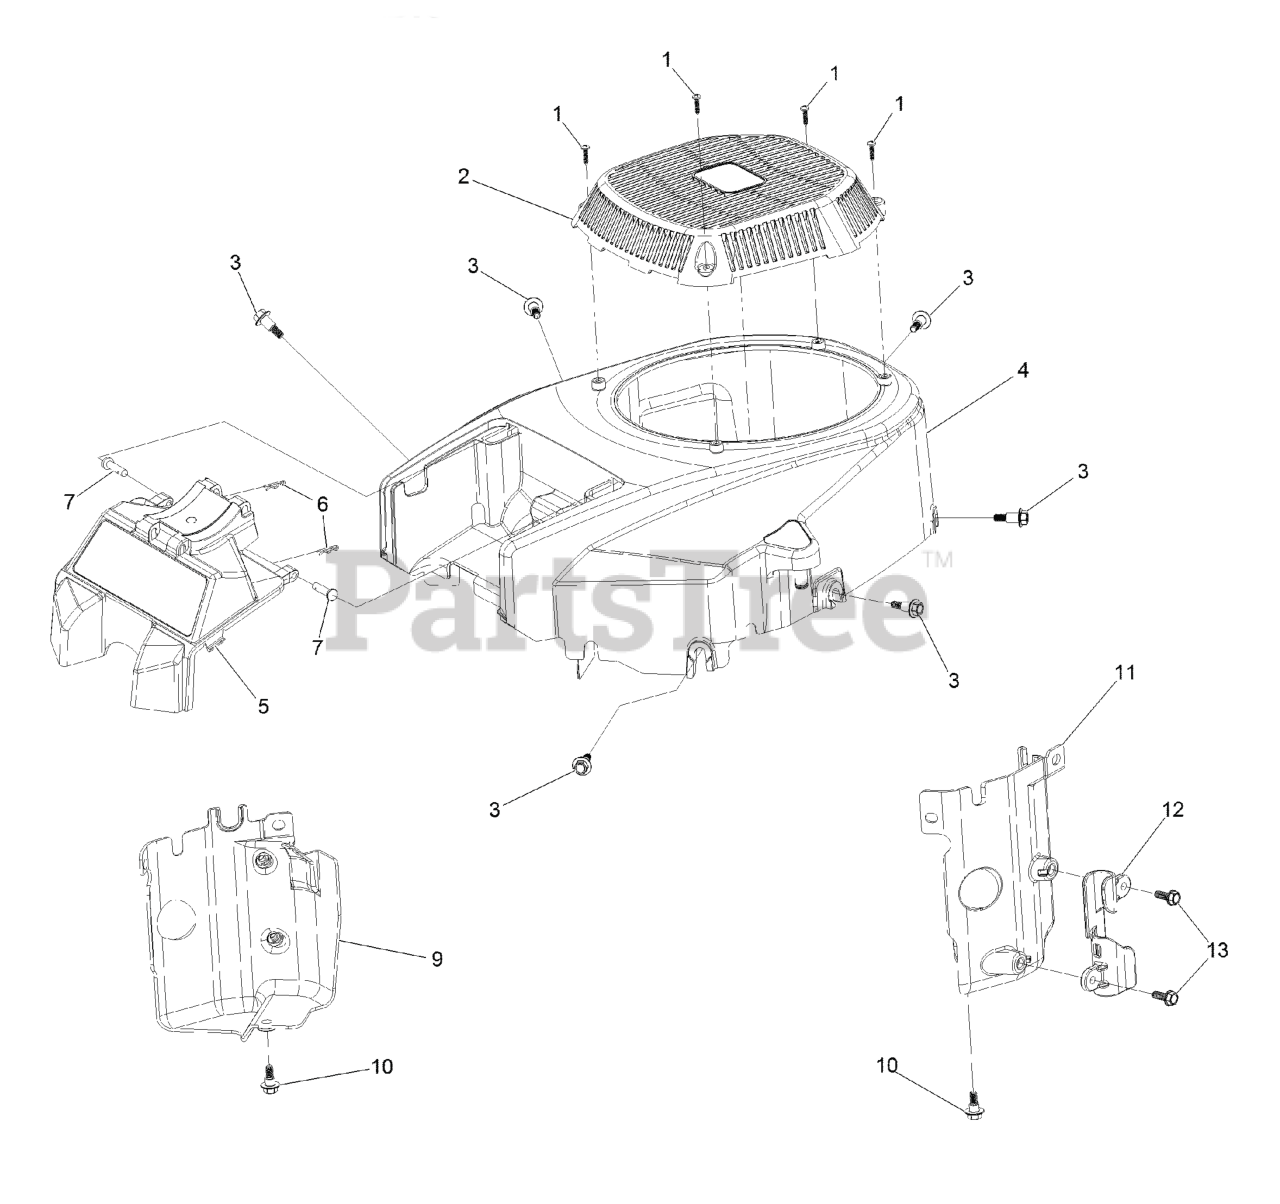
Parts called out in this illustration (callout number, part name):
1	SCREW-PPH, PLASTIC
2	COVER-FAN
3	SCREW-SHOULDER, HWH
4	SHROUD-ENGINE
5	SUPPORT-FILTER
6	PIN-HAIR
9	BAFFLE-AIR, LEFT
10	SCREW-SHOULDER, HHF
11	BAFFLE-AIR, RIGHT
12	CLEAT-HOSE
13	SCREW-HHF
